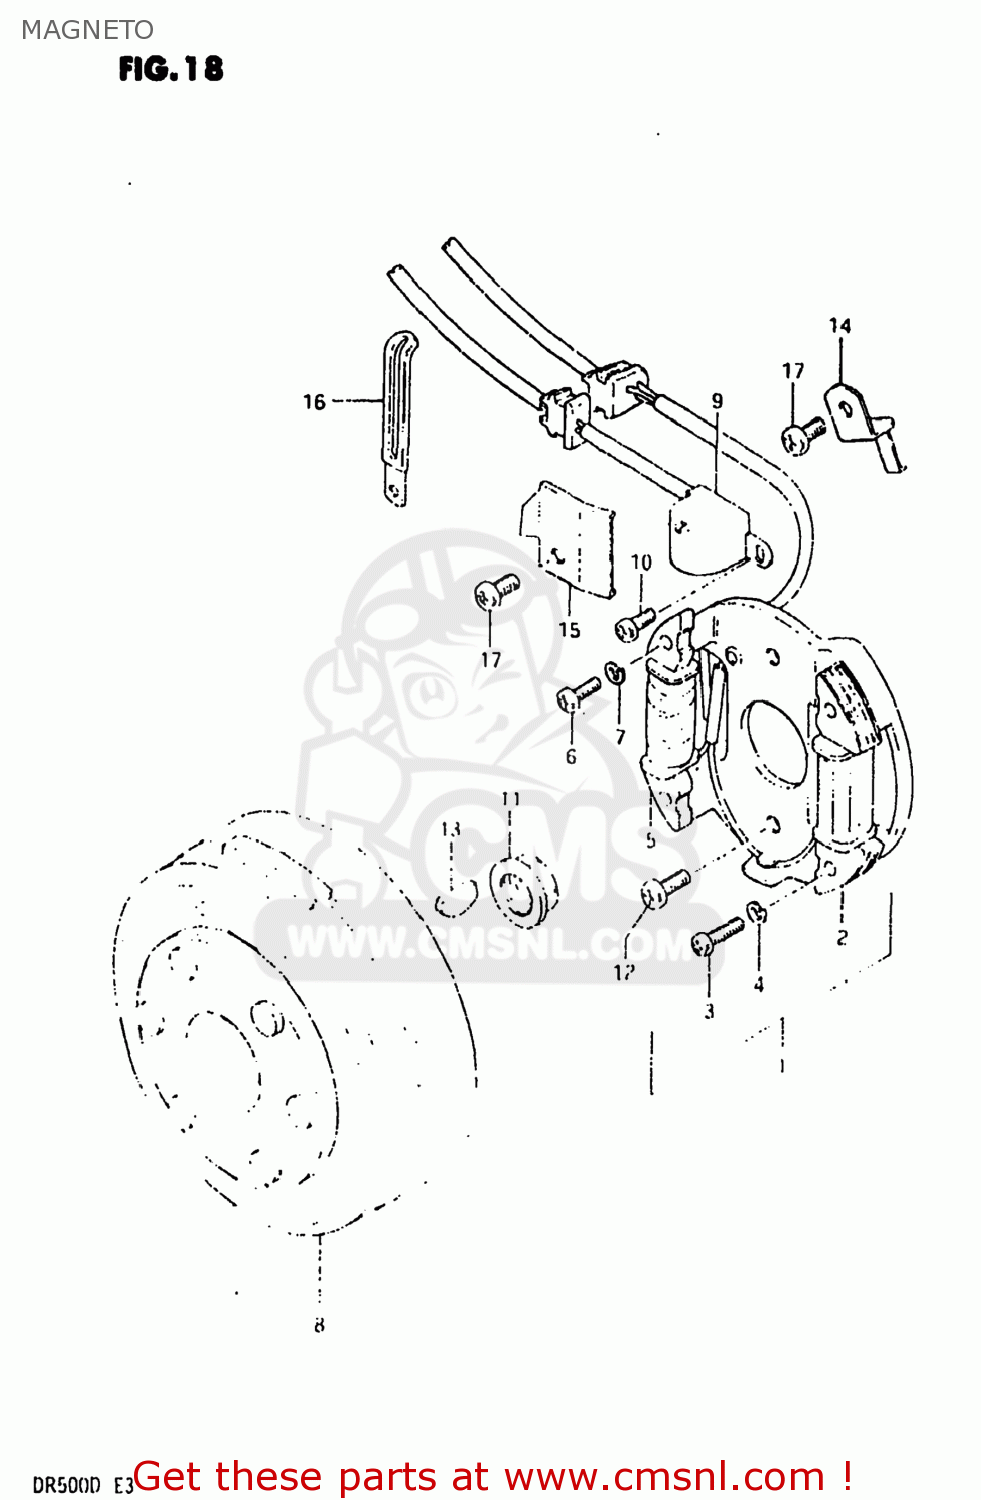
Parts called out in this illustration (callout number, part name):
1	STATOR ASSEMBLY
2	COIL,LIGHTING
3	SCREW 5X20
4	LOCK WASHER
5	COIL,PRIMARY
6	SCREW
7	LOCK WASHER
8	ROTOR,FLYWHEEL
9	COIL ASSY,PICK UP
10	SCREW (SUS)
11	NUT,GENERATOR ROTOR
12	SCREW
13	KEY 4MM
14	CLAMP,MAGNETO LEAD WIRE
15	CLAMP,MAGNETO LEAD WIRE
16	CLAMP
17	SCREW
